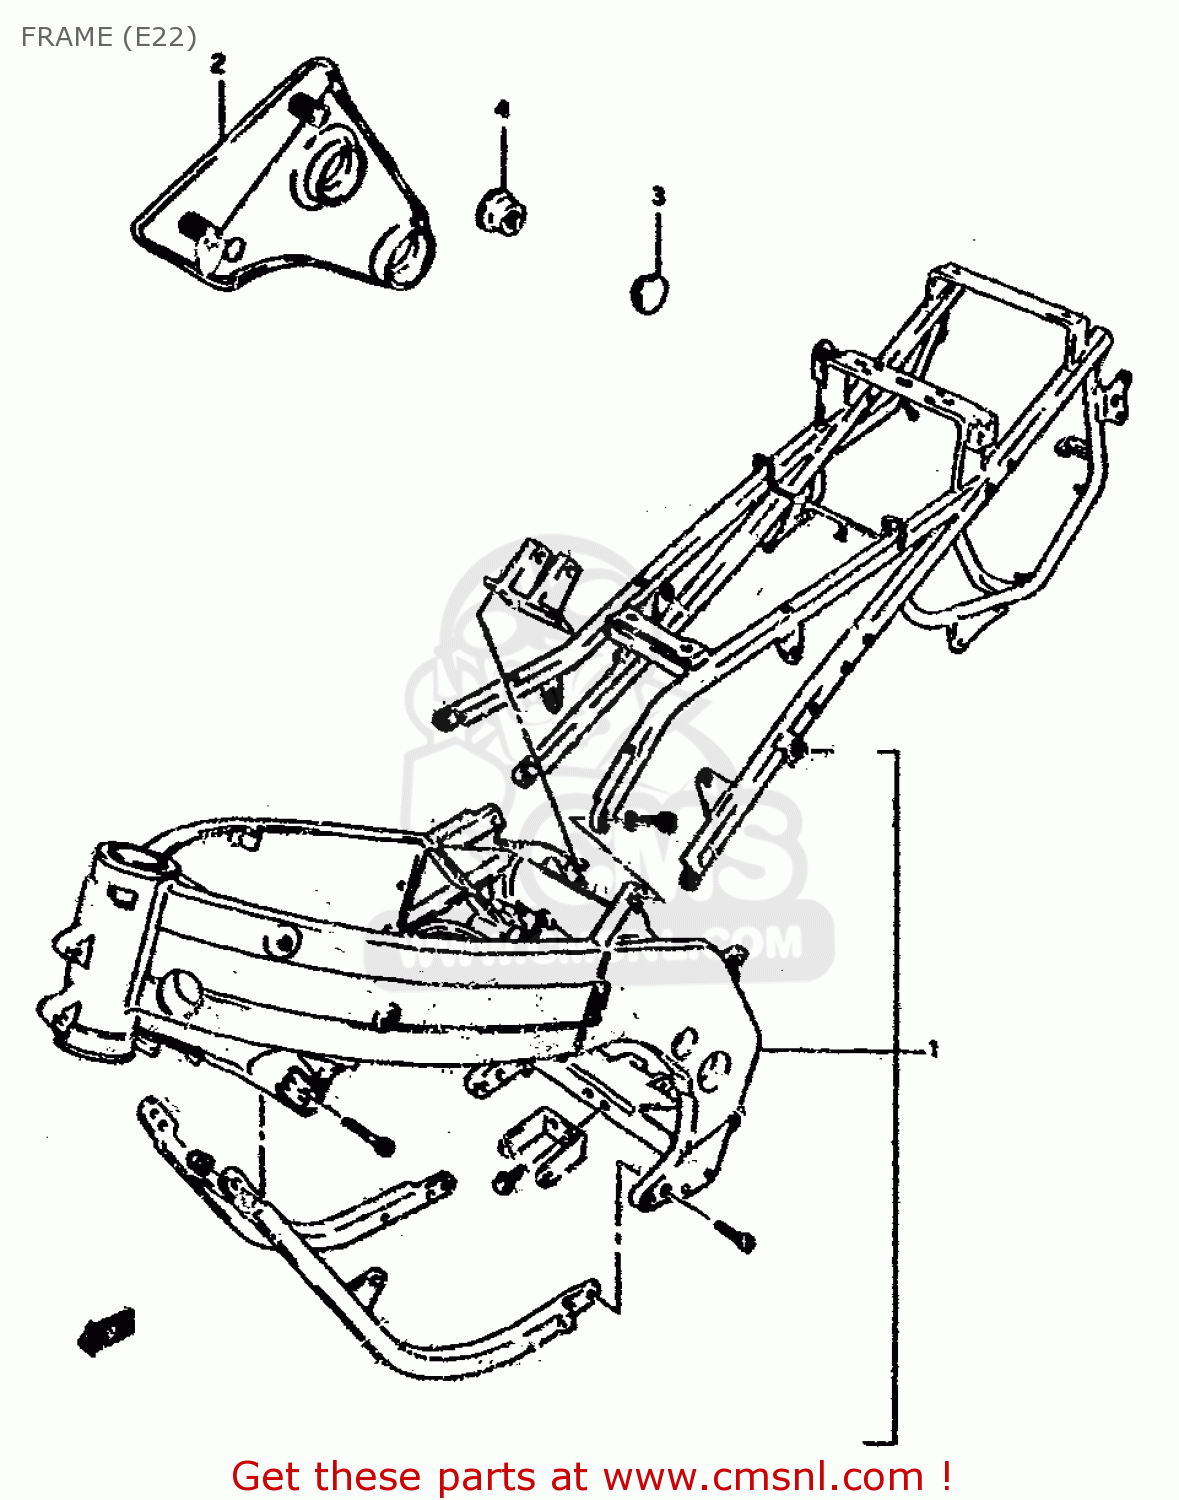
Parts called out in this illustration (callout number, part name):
1	FRAME SET
2	BRACKET, PILLION RH
3	CAP(OD:20)
4	NUT
